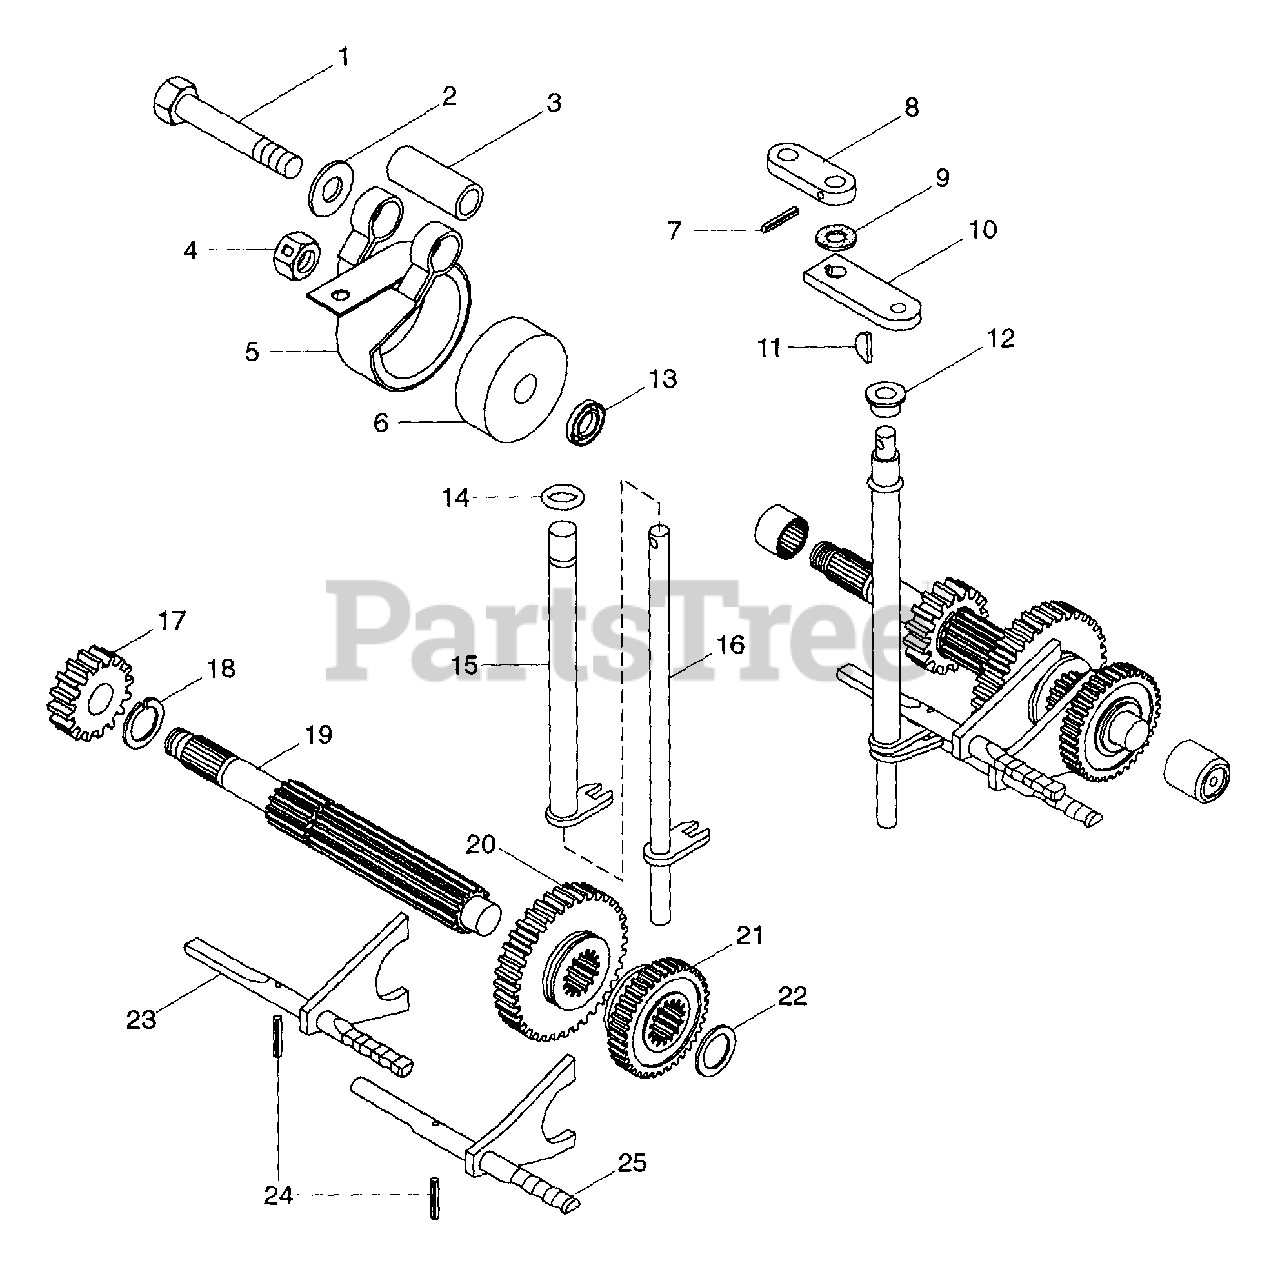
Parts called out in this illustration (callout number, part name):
1	Bolt-Hex .50-13 x 2.75 Grade 5
2	Washer-Flat-Steel .531 x 1.062 x .095
3	Bushing-Sleeve .550 x .750 x 2.06
4	Nut-Locking-Center .625-11 Grade 2
5	Assembly, Brake Band
6	Drum, Brake
7	Pin, Roll .187 x 1.000
8	Arm, Shifter
9	Washer-Felt .437 x 1.000 x .031
10	Arm, Shifter
11	key, Woodruff .13 x .38
12	Bushing-Flange .756 x 1.125 x .75
13	Seal .750 x 1.250 x .136
14	O-Ring .625 x .75 x .062
15	Weldment, 1st & 3rd Shifter
16	Weldment, 2nd & 4th Shifter
17	Gear, 8 DP 16 Teeth x .850
18	Ring-Retaining External .920 x .125
19	Shaft, Slide Gear
20	Gear, Sliding 10 DP 36 T x .594
21	Gear, Sliding 10 DP 30 T x .594
22	Bearing-N-Thrust .752 x 1.24 x .093
23	Weldment, Rail Shift Fork 1 & 3
24	Pin-Roll .250 x .75
25	Weldment, Rail Shift Fork 2 & 4
